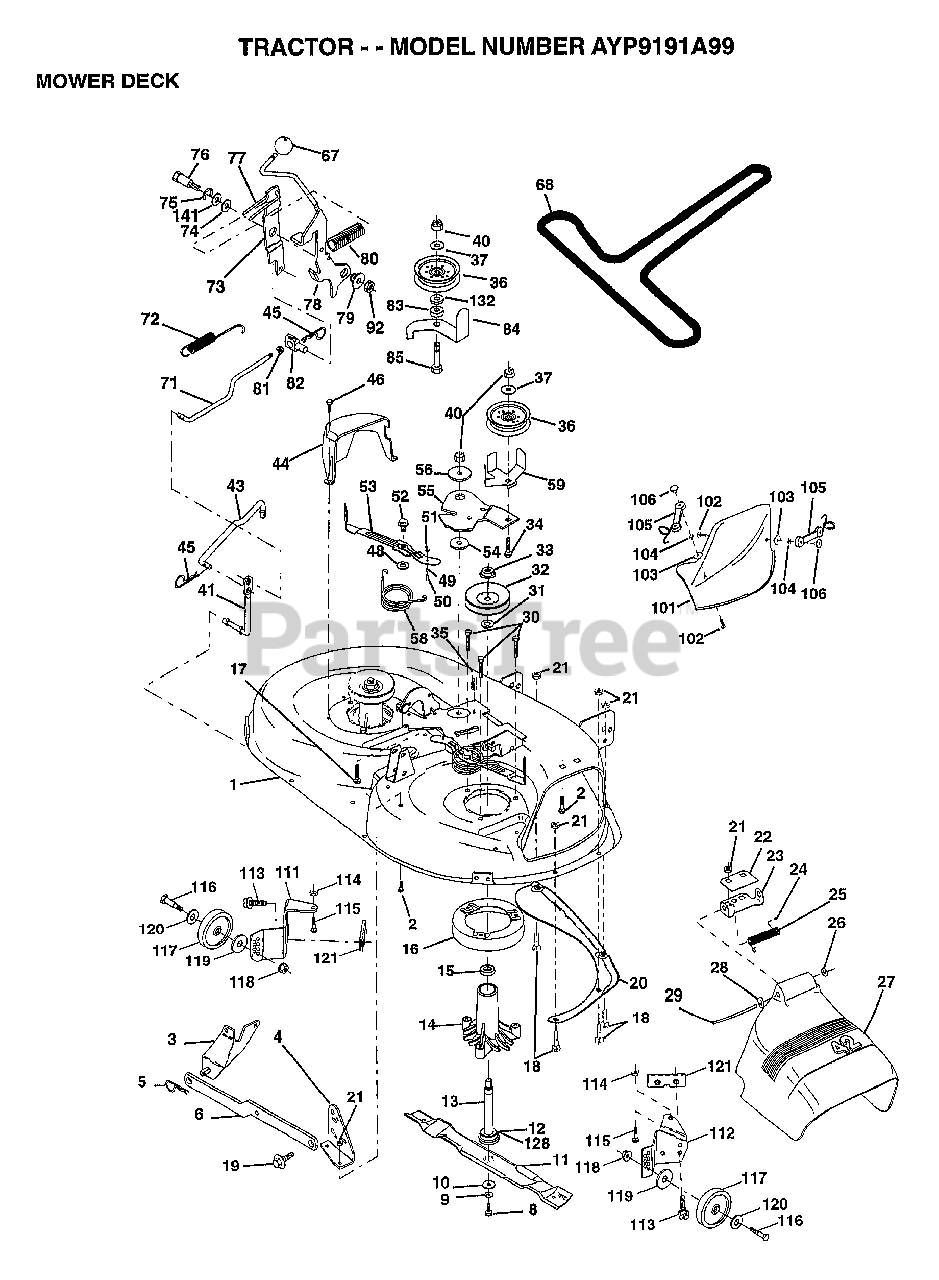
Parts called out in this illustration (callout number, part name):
1	"HOUSING ASSY.42"""
2	BOLT
3	BRKT ASM SWAY BAR
4	BRKT DECK SW BAR
8	BLADE BOLT
10	WASHER.HARD.BLADE
11	"BLADE.42"" MULCHER"
12	BEARING.BALL
14	HSG ASM MANDREL
15	BEARING
16	STRIPPER RND MWR
17	BOLT RDHD 3/8-16
18	BOLT
19	BOLT SHD 5/16-18
20	BAFFLE VORTEX 42
22	STIFFENER BRKT
23	DEFLECTOR BRKT
24	CAP-SLEEVE LT
25	SPRING TORSION
26	NUT PUSH M
27	DEFLECTOR.SHIELD
28	WASHER
29	HINGE ROD
30	"SCREW-THD ROLL,WA"
31	WASHER
32	PULLEY.MANDREL.42
34	BOLT
35	XMAS TREE FASTNER
36	FLAT IDLER PULLEY
37	WASHER
41	PIVOT ROD
43	ROD CLUTCH W/NIBS
44	GUARD MAND LH BLK
45	RETAINER M
46	SCREW.1/4-20X5/8
48	HARD SMALL WASHER
49	ROLLER ASM-CAM
50	SHOULDER BOLT
51	LOCKNUT
52	BOLT.SHLD.5/16-18
53	BRAKE PAD ARM ASM
54	HARDENED WASHER
55	ARM-IDLER
56	SPACER RETAINER
58	SPRING TORSN BRAK
59	GUARD IDLER TUV
67	KNOB.RD.7/16-14
68	BELT.V.T-PATH
71	ROD CLUTCH 38/42
72	RETURN SPRING
73	CLUTCH ARM SECOND
74	WASHER
75	RING
76	SHOULDER BOLT
77	SPRING KEEPER
78	LEVER.ASM.CLUTCH
79	BUSHING
80	SPRING.CLUTCH.MWR
81	NUT
82	TRUNION ADJ
83	WASHER
84	"KEEPER-BELT,FIXED"
85	BOLT
92	NUT
101	"COVER.MULCH.42"""
102	SCREW
103	WASHER #10
104	LOCKWASHER
105	LATCH ASSY.BAGGER
106	WELDNUT
111	BRACKET.GWHL.LH.
112	BRACKET.GWHL.RH.
113	SCREW
116	BOLT M
117	WHEEL.GAGE.BLK.PL
118	LOCKNUT
119	WASHER
120	WASHER
121	BRACKET.EXTRD.GWL
128	WASHER.FELT.
132	WASHER GT
141	WASHER .T
